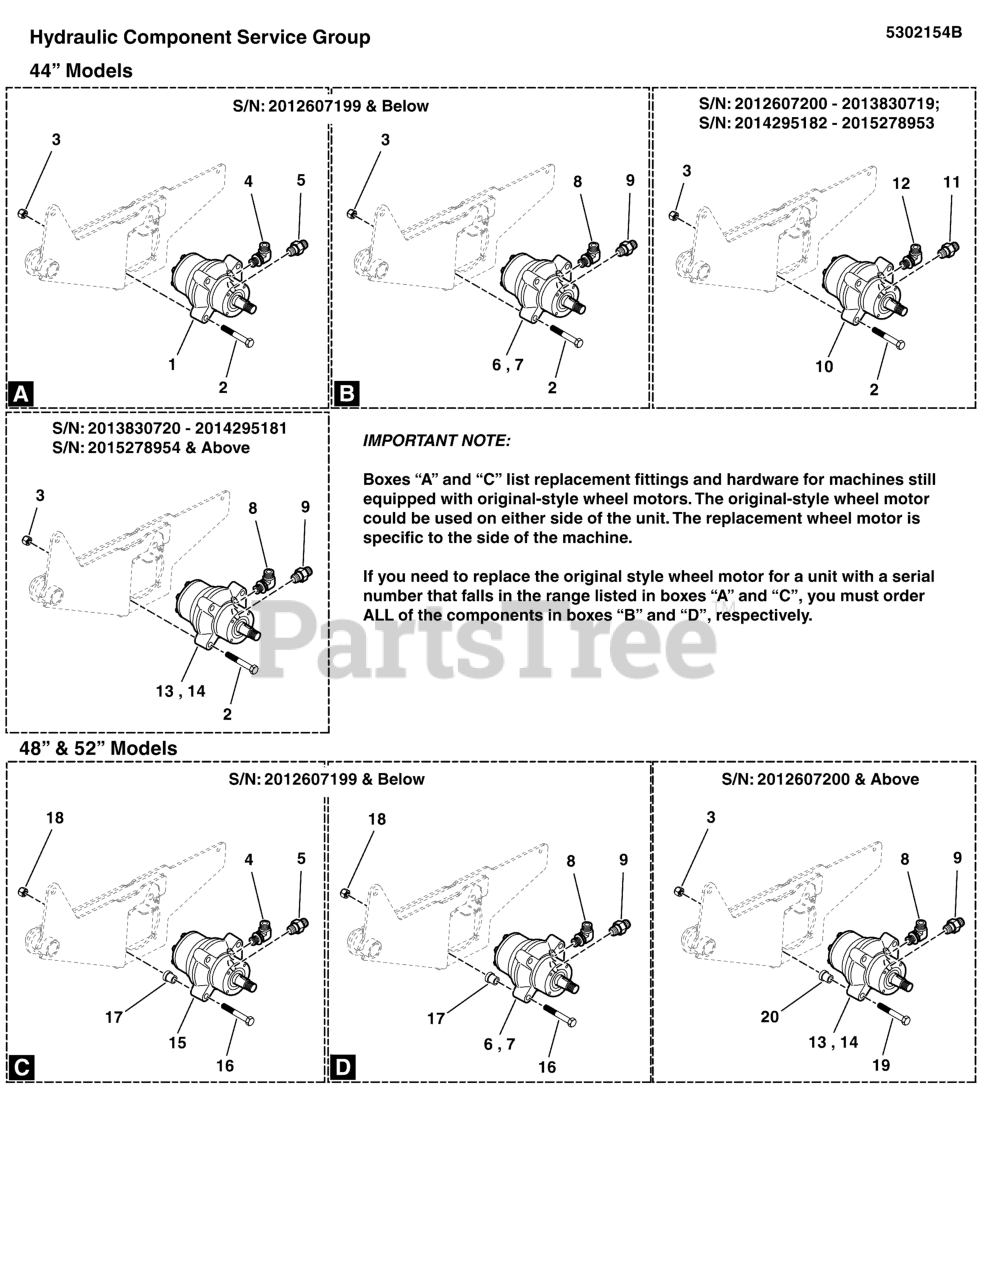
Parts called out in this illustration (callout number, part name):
2	BOLT, 1/2-13 X 2-1/4 PATCH
3	NUT, 1/2-13 SQUARE
4	FITTING, #8 JIC - #8 O-RING, 90 DEG.
5	FITTING, #8 O-RING X #8 JIC, STR
8	FITTING, #10 ORING-#8 JIC, 90D
9	FITTING, #10 O-RING X #8 JIC, STR
10	MOTOR, WHEEL, HGM-15C-4026
11	FITTING, #8 O-RING X #8 JIC, STR
12	FITTING, #8 JIC - #8 O-RING, 90 DEG.
13	WHEEL MOTOR, LH, 14.5 CI-TF0240LS080AAKZ
14	WHEEL MOTOR, RH, 14.5 CI-TF0240LS081AAKZ
16	BOLT, 1/2-13 X 3-1/2, HEX HD, GD5, CZ (SV)
17	SPACER, .53 X 1.00 X 1.00, CZ
18	NUT, Hex Flange, Nylock, 1/2-13
19	BOLT, 1/2-13 X 3.5, DRI-LOC PATCH
20	SPACER, .53 X 1.00 X 1.00, W/ FLAT, CZ
